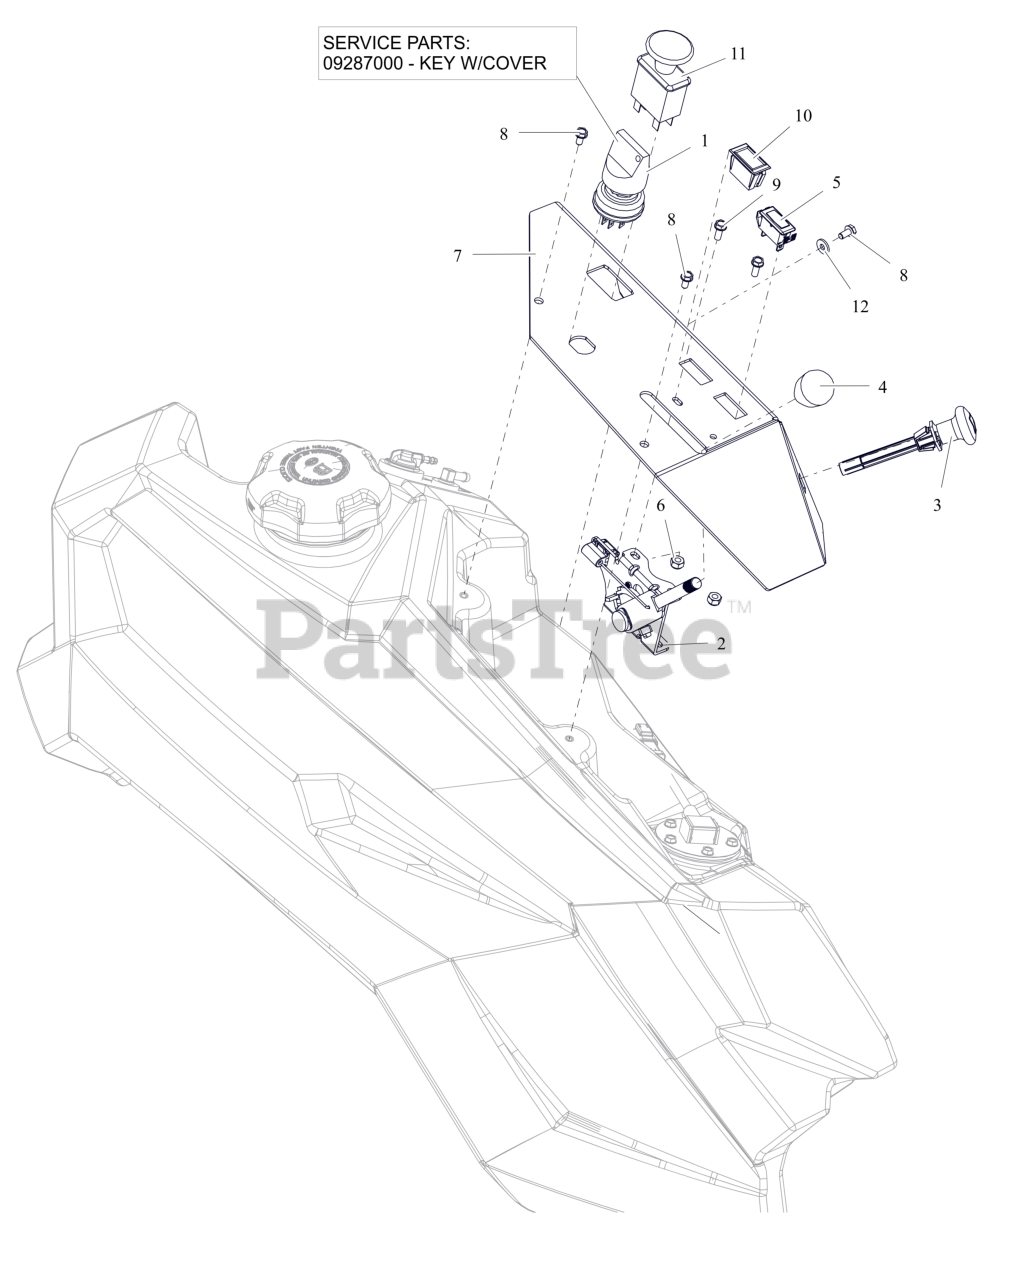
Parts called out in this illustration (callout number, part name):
1	SWITCH, IGNITION
1	KEY, W/ SHIELD
2	CABLE, PRO-CTRL 46.00"
3	CABLE, CHOKE (SNAP IN)
4	KNOB-CONTROL-BLACK .38-16X.50
5	LIGHT, INDICATOR (RED)
6	NUT-LK-NYL #10-24 G2 ZCC
7	PANEL, RH CONTROL (RED)
8	SCR-MCH 10-24X.38 HWHSTAINLESS
9	BLT, HWH #10-24X.50 ZCC
10	SWITCH,BLANK
11	SWITCH, CLUTCH
12	WSHR-FL-STL .196X.50X.06 ZC120
